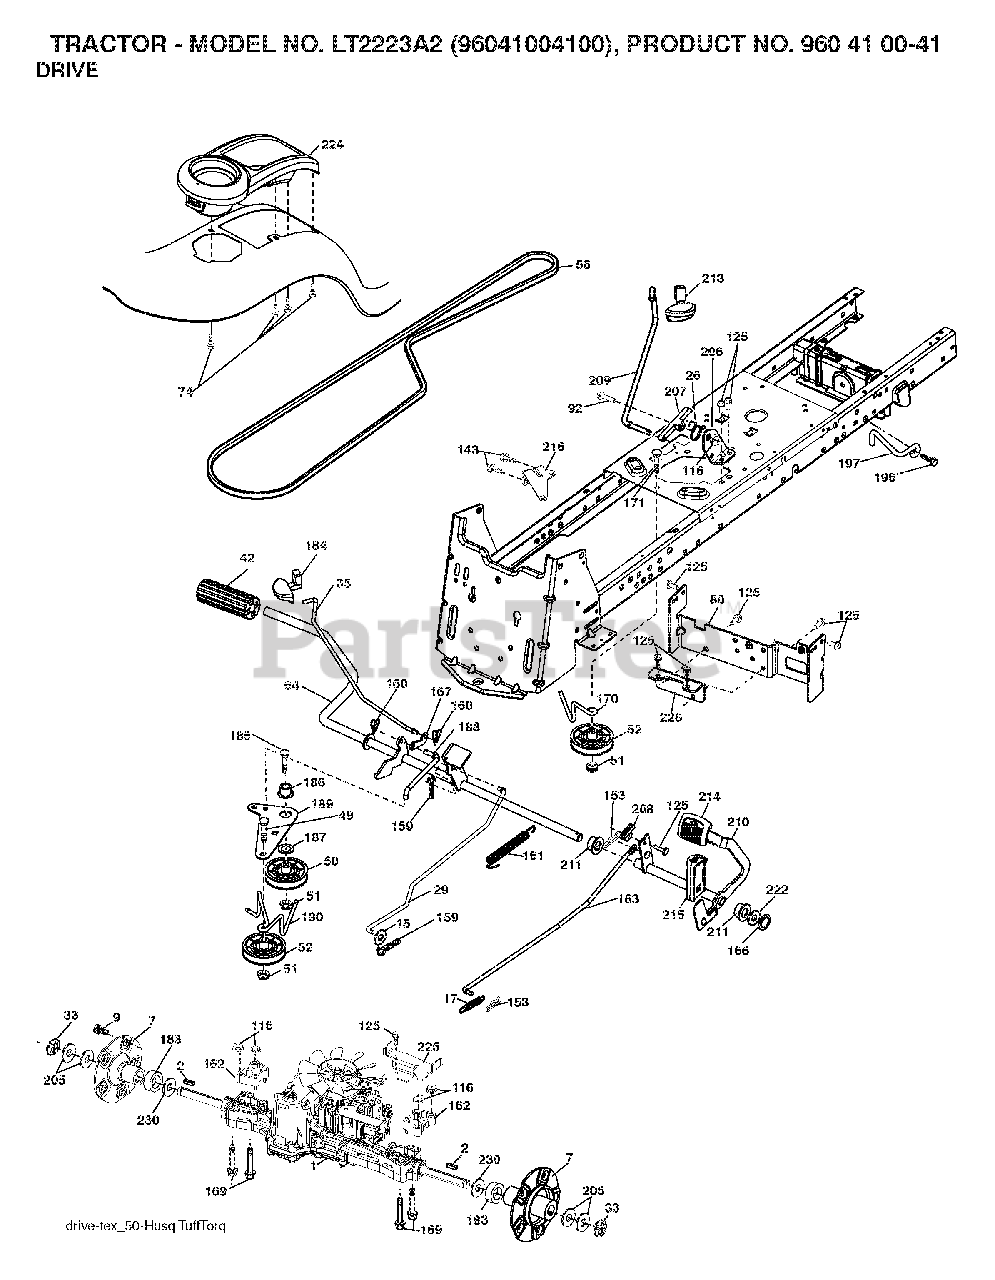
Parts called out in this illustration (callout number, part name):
1	TRANSAXLE.K46BN.PEDAL CONTROL
2	KEY.SQUARE.187X2.500
7	HUB.ASM.WHEEL.REAR.22"
9	HUB BOLT
17	SPRING.BRAKE.K46.GREEN
26	SPRING.RETURN.CRUISE
29	ROD.BRAKE.K46
33	E-RING LT
35	ROD.BRKAE.PARKING.STEALTH
42	PEDAL COVER T
49	BOLT
50	IDLER.FLAT.910.OFFSET
51	NUT LOCK FLG 3/8-16 UNC
52	IDLER.V-GROOVE.910.OFFSET
64	SHAFT.ASM.PEDAL.BRK.CNTR
74	SCREW.HI-LO.CONSOLE
80	STRAP.TORQUE.HG3000/K46
92	BOLT
116	NUT LOCK HEX FLANGE 5/16-18
125	SCREW
143	SCREW LT
153	RETAINER M
159	COTTER PIN
160	RETAINER CLIP
161	SPRING.RETURN.CLUTCH.2006
162	SPACER.TRANSAXLE.18&22
163	ROD.CONTROL.PEDAL.K46
166	NUT.PUSH.625.2006
167	LATCH.BRAKE.SPRING
169	BOLT.HEX.FLNG.5/16-18X3.75
170	KEEPER.V-IDLER.CENTER.
171	BOLT
183	SPACER.SPLIT.800X.350
184	HANDLE.PRKG.BRAKE.STLTH.TX.RED
185	BOLT
186	SPACER.RETAINER
187	WASHER 12/32X2X10GA
188	LINK.CLUTCH.GROUND.DRIVE
189	BELLCRANK.GROUND.DRIVE.TEX.
190	KEEPER.BELLCRANK.DRIVE
196	SCREW 3/8-16X1
197	BRKT.ANIT-ROTATION.CLU
206	BRKT.MOUNT.LATCH.CRUIS
207	LATCH.CONTROL.CRUISE
208	GEAR.SECTOR.CONTROL.CR
209	ROD.CONTROL.CRUISE.STEALTH.TEX
210	ROCKER.ASM.PEDAL.CONTR
211	BEARING.NYLON
213	KNOB.CONTROL.CRUISE
214	PEDAL.FORWARD.TEX.GT.4
215	PEDAL.REVERSE.TEX.GT.4
216	BRACKET.PULLEY.IDLER.W/TEX
222	WASHER 21/32 X 1-1/4 X 10 GA.
224	CONSOLE.TOOLBOX.PCH.ERGO.BLACK
225	KEEPER.BELT.TRANSAXLE.K46
226	BRKT.MOUNT.TORQUE.K46.
230	WASHER.HARDENED
